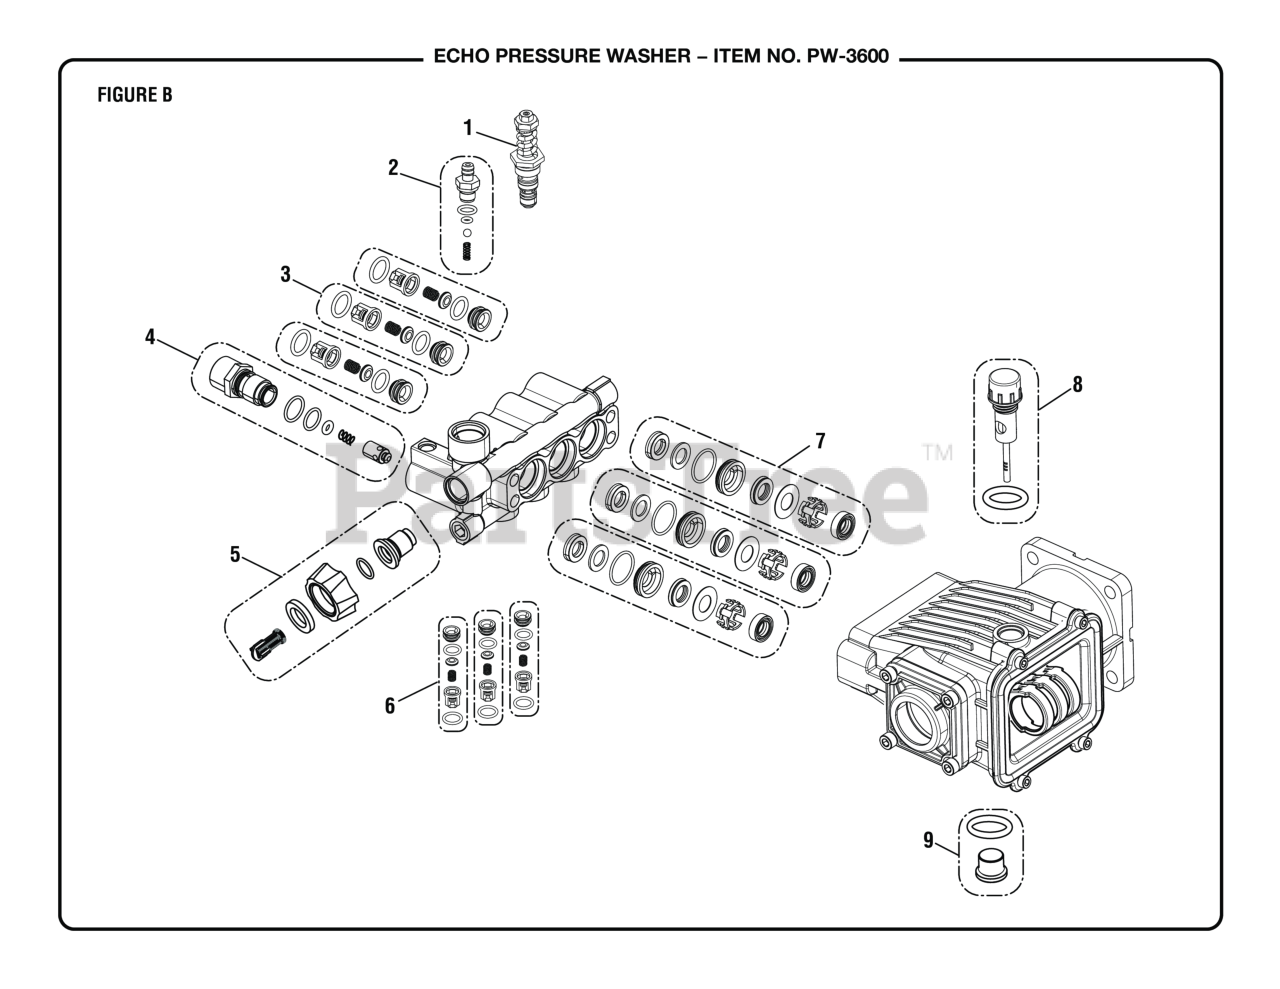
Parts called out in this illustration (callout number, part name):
1	ASSY., UNLOADER
2	KIT, SOAP INJECTOR
3	KIT, INLET VALVE
4	KIT, QC OUTLET CONNECTOR
5	KIT, INLET ASSEMBLY
6	KIT, OUTLET VALVE
7	KIT, PRESSURE SEAL
8	KIT, VENT PLUG
9	KIT, OIL PLUG
